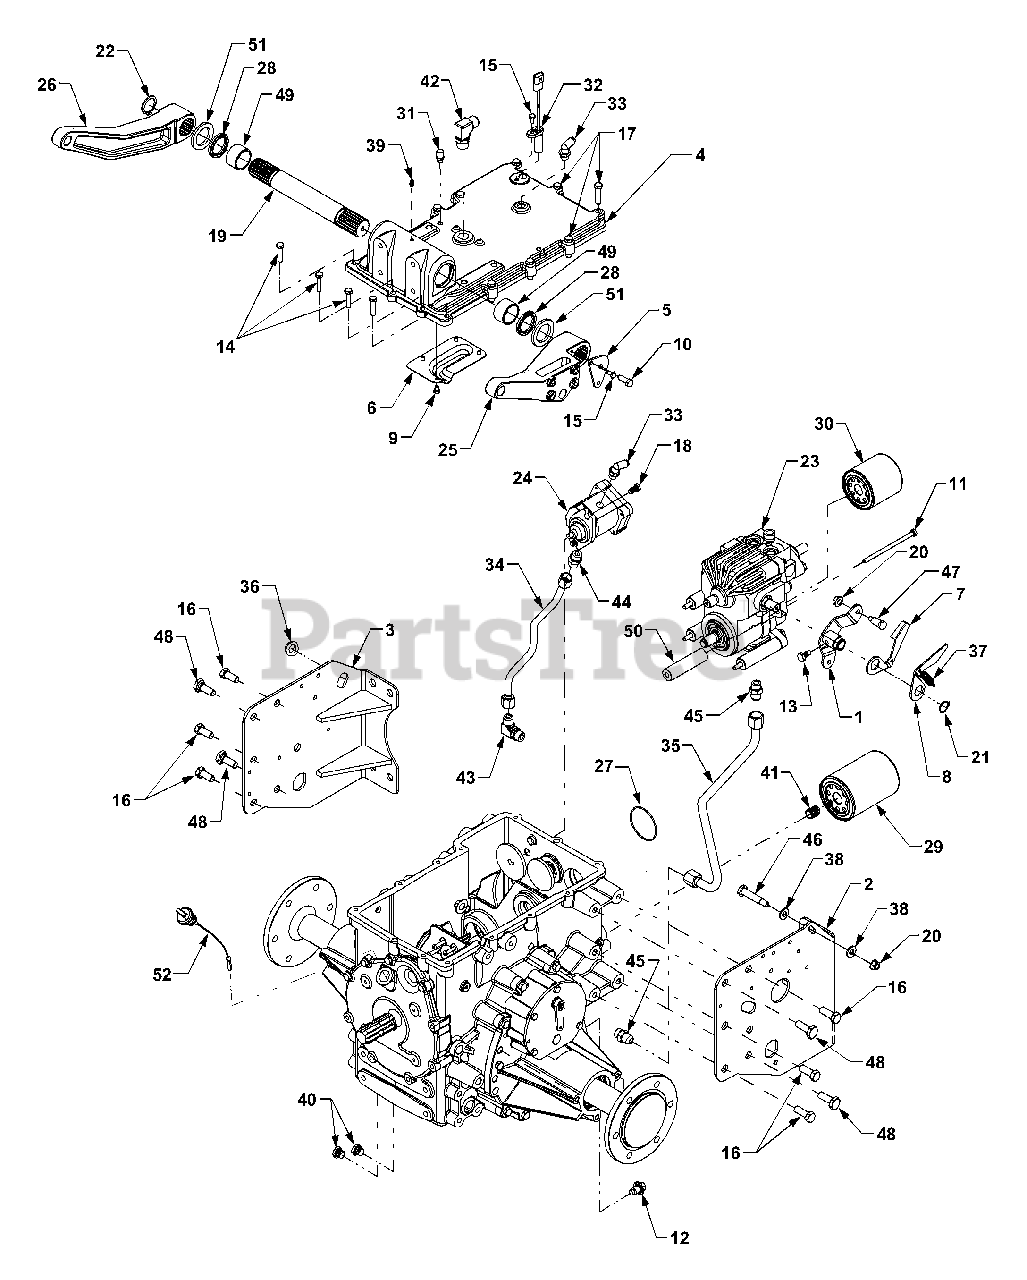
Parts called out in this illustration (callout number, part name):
1	Arm, Hydro Control
2	Bracket, Transmission Mtg. RH
4	Cover, Transmission Housing
5	Plate, Feedback
6	Baffle, Oil
7	Arm, Neutral RH
8	Arm, Neutral LH
9	Screw, Hex Cap, 1/4-20 x .375 GR5
10	Screw, Hex Cap Lock, 3.8-24 x 1.0 GR5
11	Screw, Hex Cap, 5/16-18 x 5.25 GR5
12	Screw, Plug, M14 x 1.5 x .827
13	Screw, Hex Special Set, 5/16-18 x .625
14	Screw, Hex Cap, 3/8-16 x 1.25 GR5
15	Screw, Hex Cap, 1/4-20 x .5 GR5
16	Screw, Hex Cap, 1/2-13 x 1.25 GR5
17	Screw, Hex Cap Lock, 3/8-16 x 1.5 GR5
18	Screw, Low Hd. Cap, 3/8-16 x .75
19	Shaft, Rock
20	Nut, Hex Flange Lock, 3/8-16
21	Ring, Retaining
22	Ring, Retaining
23	Pump, Hydrostatic Transmission
24	Pump, Auxiliary Hydraulic
25	Arm, Upper Hitch RH
26	Arm, Upper Hitch LH
27	O-Ring, 2.987 ID x .103 Dia
28	Seal, Oil, 1.5 x 2.0 x .25
29	Filter, Oil, Hydraulic System
30	Filter, Oil - Hydro Pump
31	Breather, Transmission
32	Sensor, RPM
33	Fitting, 90 degrees
34	Tube, Auxiliary Pump Suction
35	Tube, Hydro Suction
37	Spring, Extension
38	Washer, Flat, .406 x 1.0 x .105
39	Fitting, Grease
40	Plug, Fitting
41	Fitting, Filter Nipple
42	Fitting, 90 degrees
43	Fitting, 90 degrees
44	Fitting, Straight
45	Fitting, Straight
46	Screw, Shoulder, .498 Dia x 1.45
47	Screw, Shoulder, .50 Dia x .685
48	Screw, Shoulder, .625 x .18: 1/2-13
49	Bearing, Sleeve, 1.52 x 1.75 x 1.0
50	Spacer, .40 x 1.0 x 3.9
51	Spacer, 1.52 x 2.25 x .188
